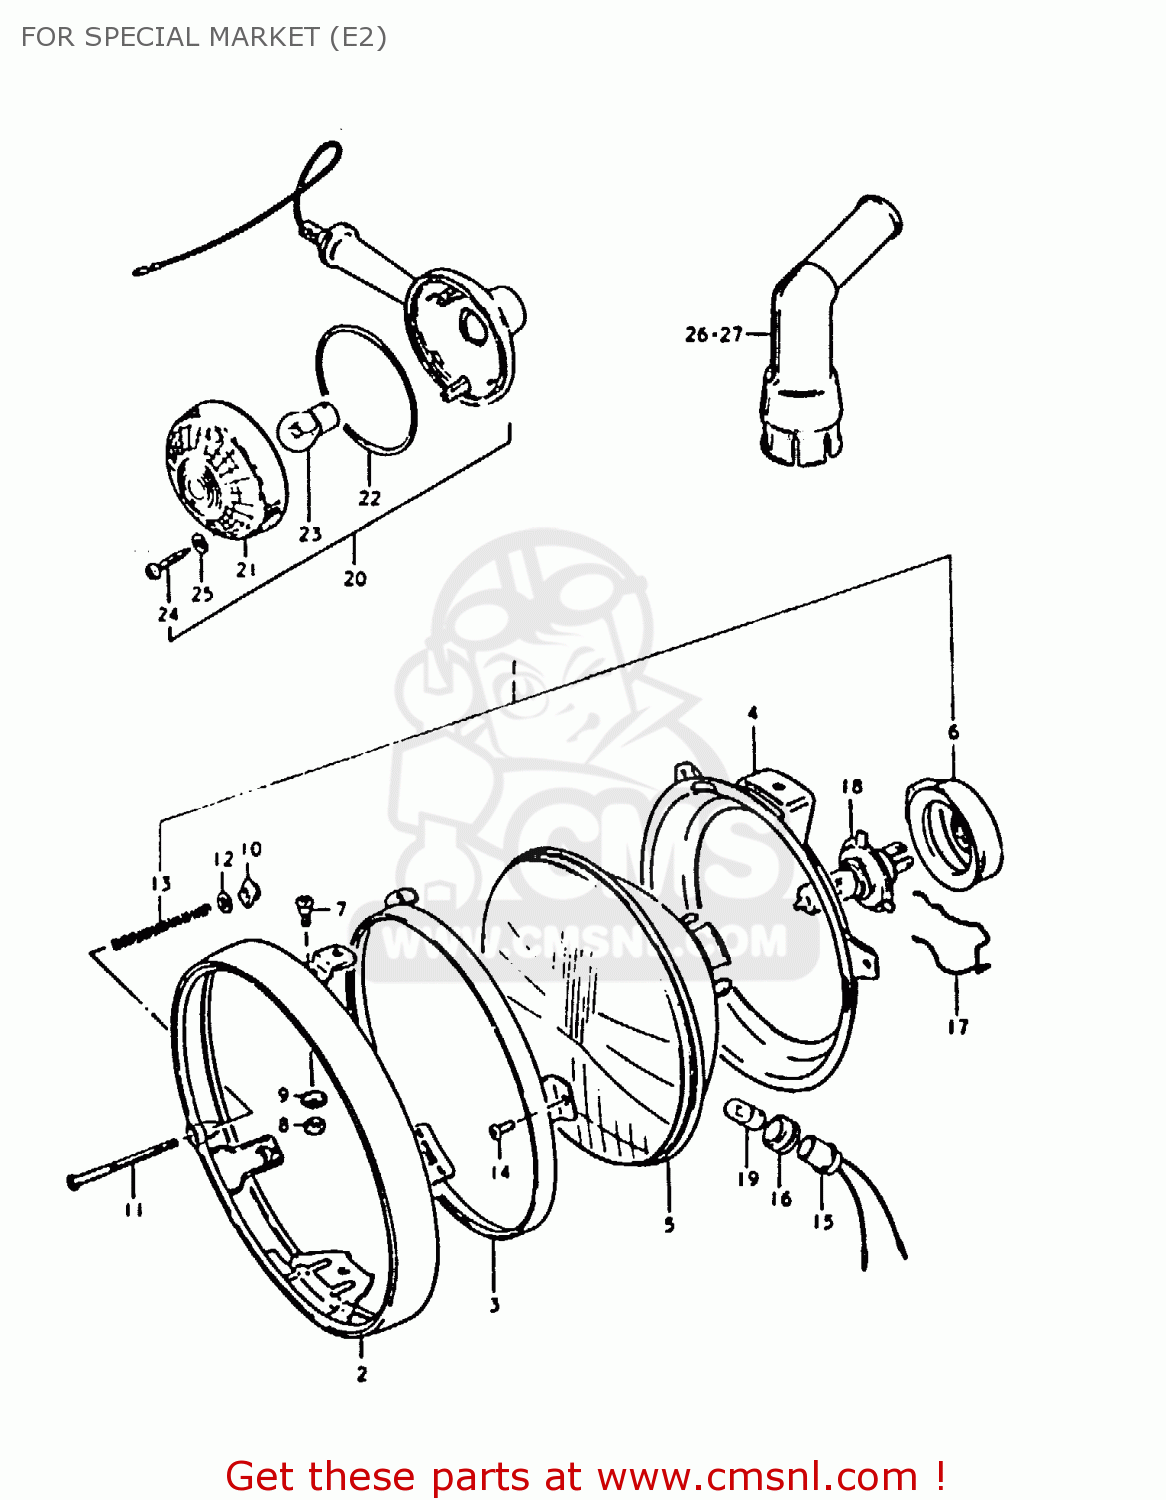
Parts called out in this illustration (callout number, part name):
1	HEADLAMP ASSY
2	RIM
3	RETAINER
4	RING,HEADLAMP UNIT
5	UNIT
6	COVER,HEADLAMP SOCKET
7	SCREW
8	NUT,ADJUSTING
9	SPACER
10	NUT
11	SCREW,HEADLAMP ADJUST
12	WASHER
13	SPRING,HEADLAMP ADJUST
14	SCREW
15	SOCKET
16	JOINT,RUBBER
17	CLAMP,HEADLAMP SOCKET
18	BULB(12V60/55W,H4)
19	BULB(12V4W)
20	LAMP ASSY, FRONT TURN SIGNAL
21	LENS
22	GASKET (NAS)
23	BULB 12V 21W
24	BOLT
25	GASKET (NAS)
26	CAP, SPARK PLUG (S)
27	CAP,SPARK PLUG
